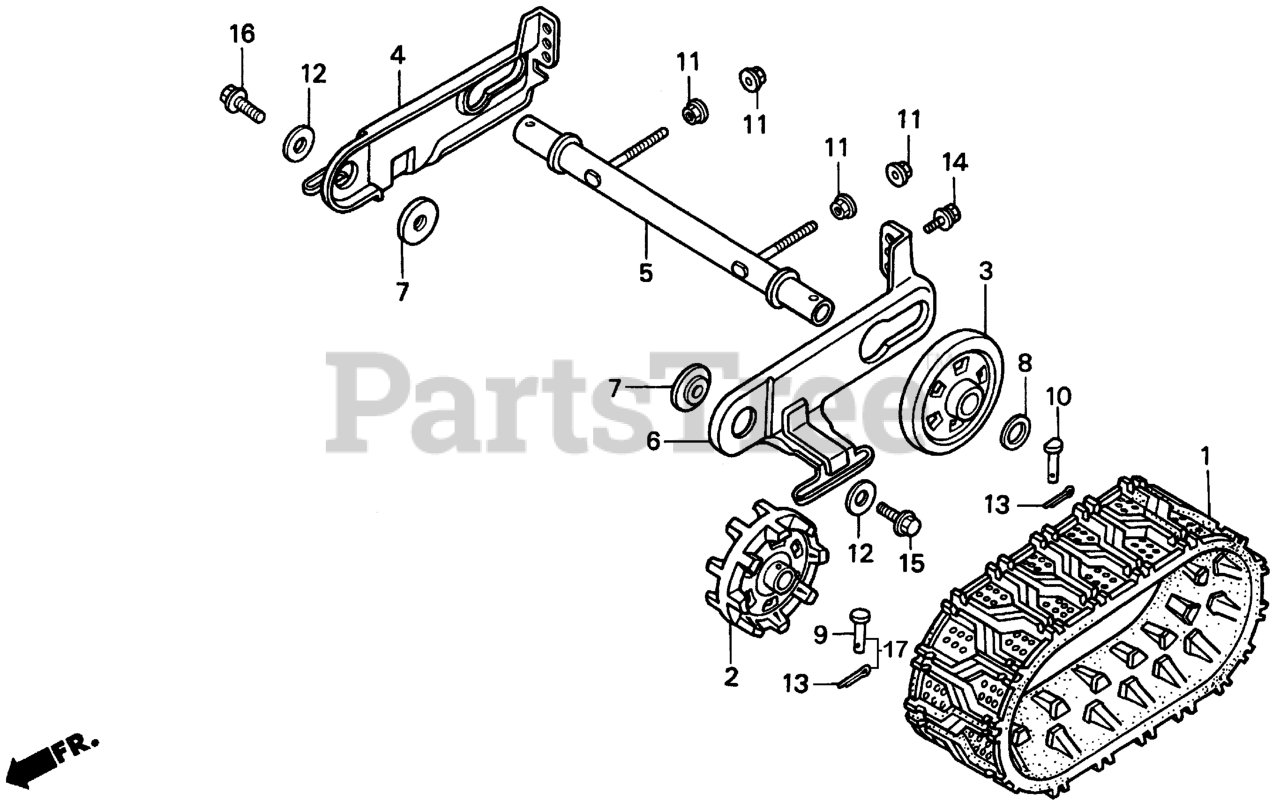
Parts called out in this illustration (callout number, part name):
2	SPROCKET, CRAWLER
3	ROLLER, CRAWLER
4	PLATE, R. CRAWLER GUIDE
5	PIPE, CRAWLER
6	PLATE, L. CRAWLER GUIDE
7	WASHER, WHEEL SHAFT
8	WASHER, PLAIN (22MM)
9	PIN (6.2X38)
11	NUT, FLANGE (10MM)
12	WASHER, PLAIN (10MM)
13	PIN, COTTER (3.0X18)
14	BOLT, FLANGE (8X16) Use from Engine SN 1000016.
15	BOLT, FLANGE (10X25)
16	BOLT, FLANGE (10X25)
